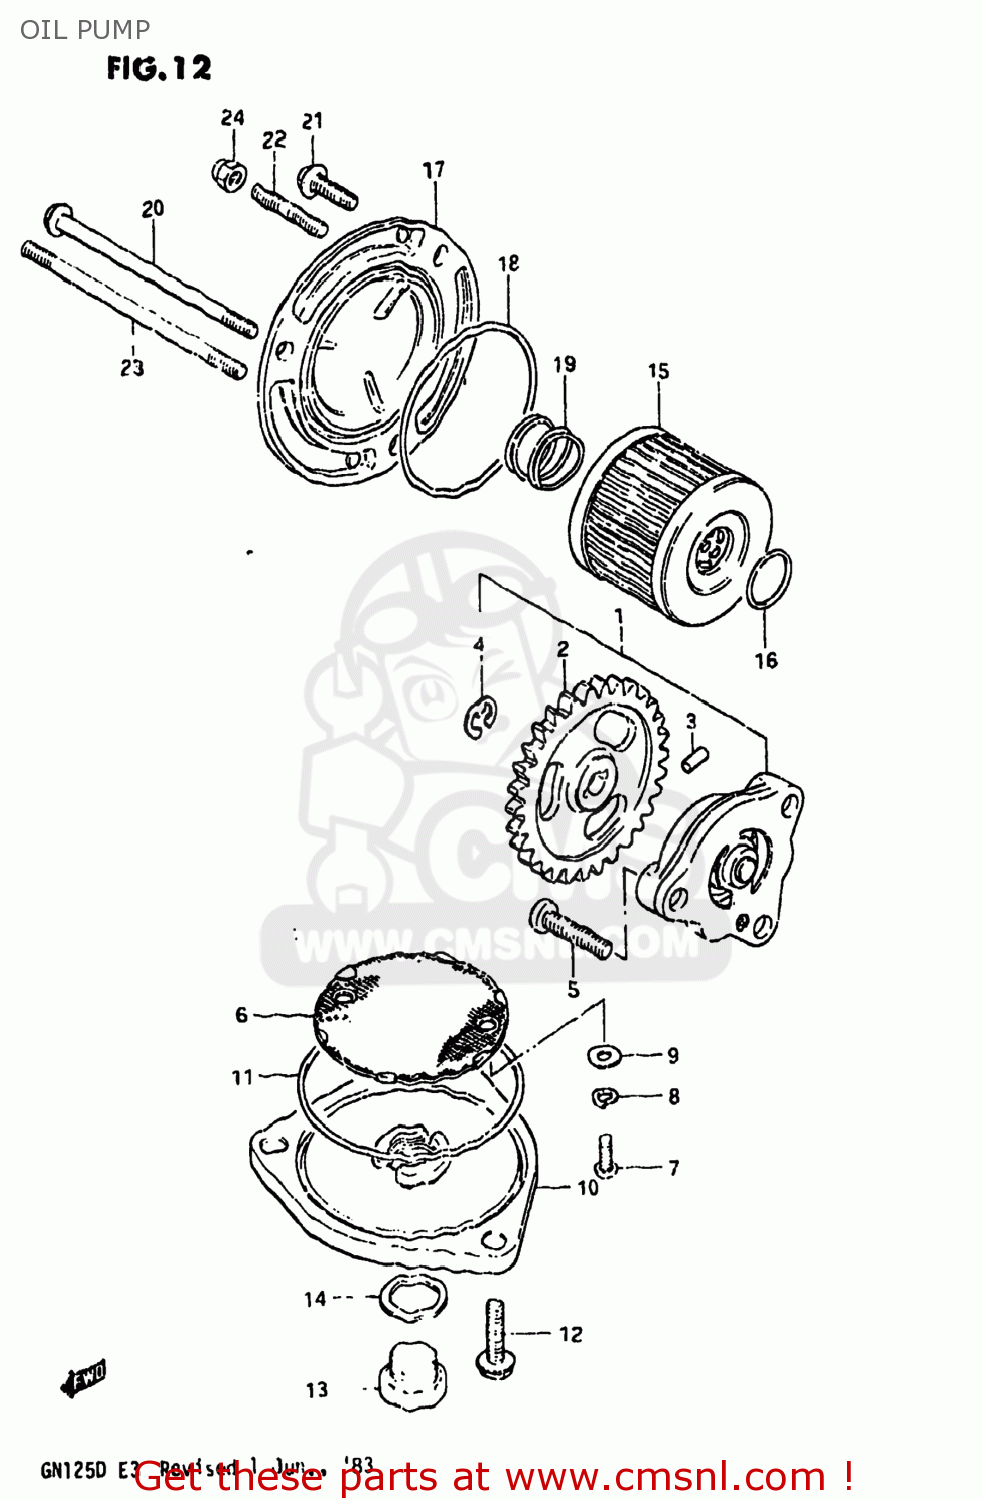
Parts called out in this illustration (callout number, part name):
1	PUMP ASSEMBLY,OIL
2	GEAR,ENG OIL PUMP DRIVEN(NT:30
3	PIN(2.5X11.8)
4	E RING 6MM
5	SCREW
6	STRAINER,ENGINE OIL
7	SCREW
8	LOCK WASHER
9	WASHER
10	CAP,OIL STRAINER
11	O RING(D:2.4,ID:60.5)
12	BOLT (6X20)
13	PLUG
14	GASKET(14X19.2X2) (NAS)
15	FILTER ASSY,ENGINE OIL
16	O RING(D:1.9,ID:13)
17	CAP,OIL FILTER
18	O RING(D:2.4,ID:52.6)
19	SPRING
20	BOLT
21	BOLT (6X20)
22	STUD 6X12
23	STUD BOLT, 6X8
24	NUT
